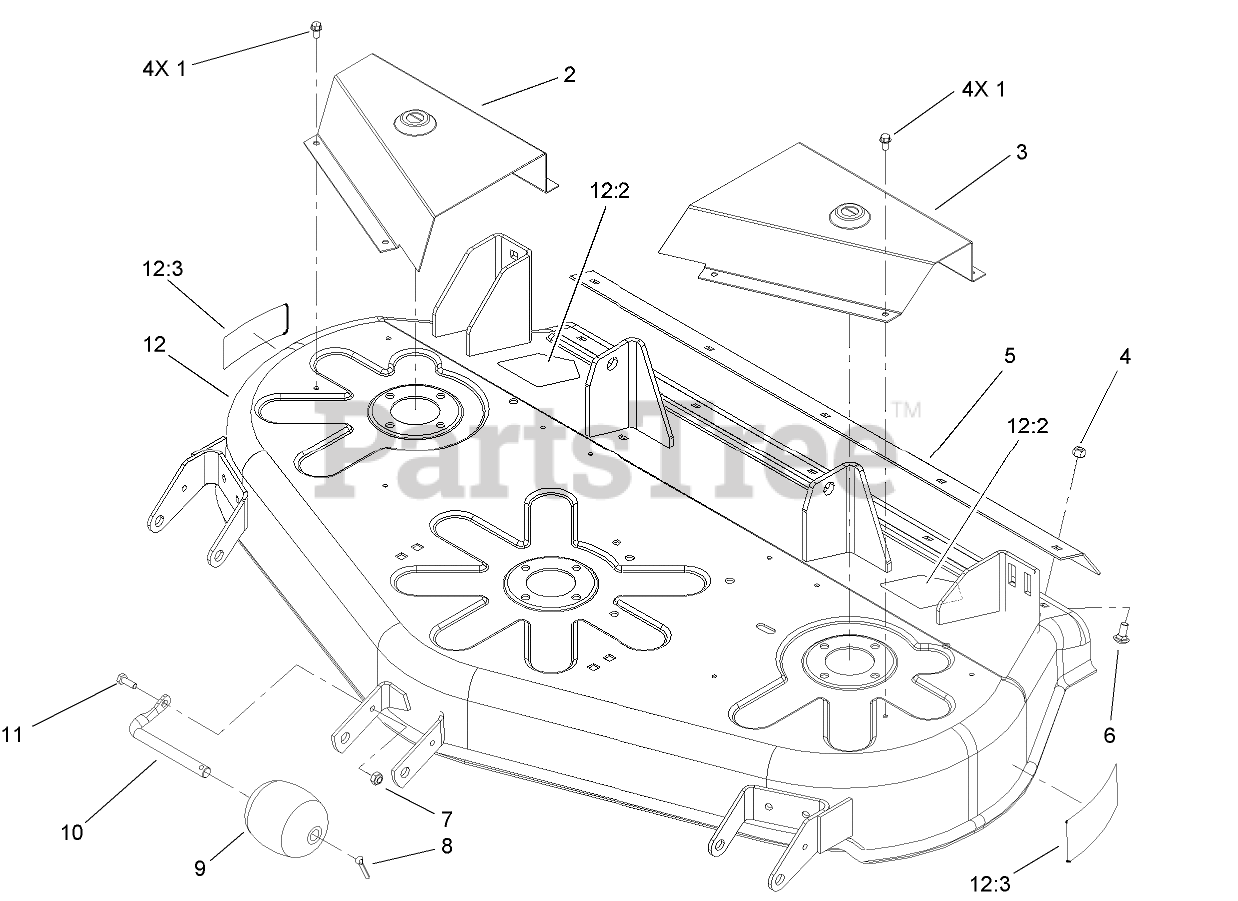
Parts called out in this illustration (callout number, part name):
1	SCREW-HWH
2	COVER-BELT, RH
3	COVER BELT, LH
4	NUT-LOCK, NI
5	DEFLECTOR
6	BOLT-CARR
7	NUT-LOCK, NI
8	PIN-COTTER
9	ROLLER
10	Shaft-Roller
11	SCREW-HH
12	DECK AND DECAL ASM
12:2	DECAL-DANGER
12:3	DECAL-DANGER
